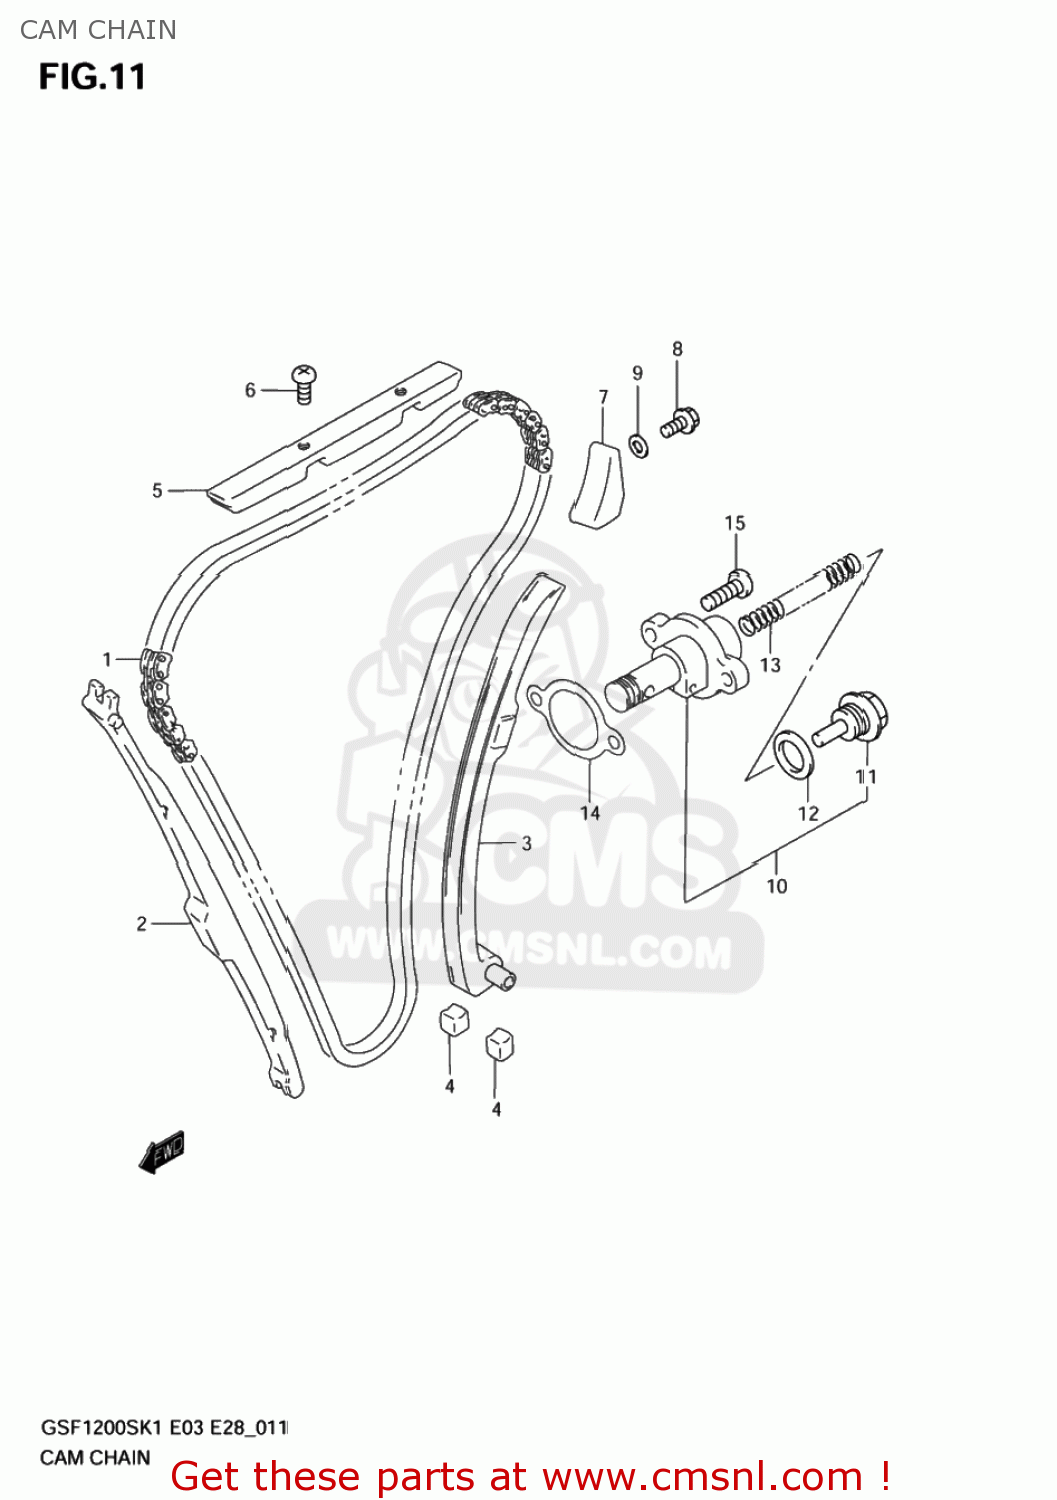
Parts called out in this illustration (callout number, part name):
1	CHAIN,CAMSHAFT DRIVE
2	GUIDE,CAM CHAIN NO.1
3	TENSIONER,CAM CHAIN
4	CUSHION,CAM CHAIN TENSIONER
5	GUIDE,RR CAM CHAIN NO.1
6	SCREW
7	GUIDE,CAM CHAIN NO.2
8	BOLT
9	GASKET(5.8X13X1.2) (NAS)
10	ADJUSTER ASSY,TENSIONER
11	PLUG
12	GASKET (NAS)
13	SPRING
14	GASKET,TENSIONER ADJUSTER (NAS)
15	BOLT,CL.COVER
